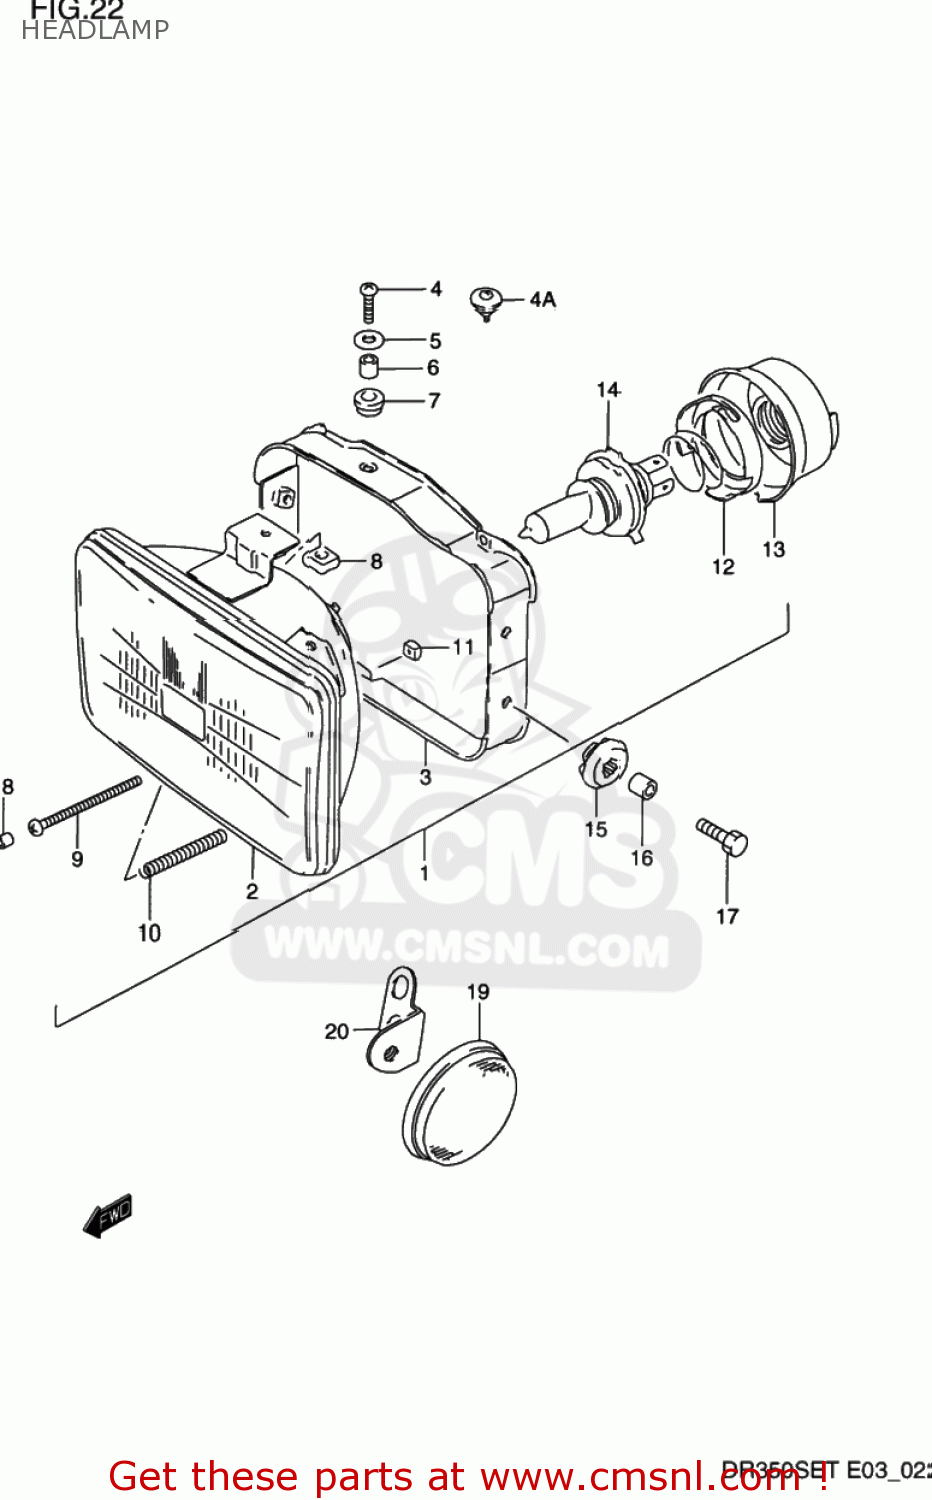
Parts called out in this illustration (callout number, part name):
1	HEADLAMP ASSEMBLY
2	LAMP UNIT
3	HOUSING
4	SCREW
4A	SCREW,MOUNTING
5	WASHER
6	SPACER
7	CUSHION
8	NUT
9	SCREW
10	SPRING
11	NUT
12	HOLDER,BULB
13	COVER,SOCKET
14	BULB(12V60/55W,H4)
15	CUSHION
16	SPACER(6.3X9.1X11.5)
17	BOLT 6X20
18	CAP,SCREW
19	REFLECTOR,REFLEX FR
20	BRACKET
